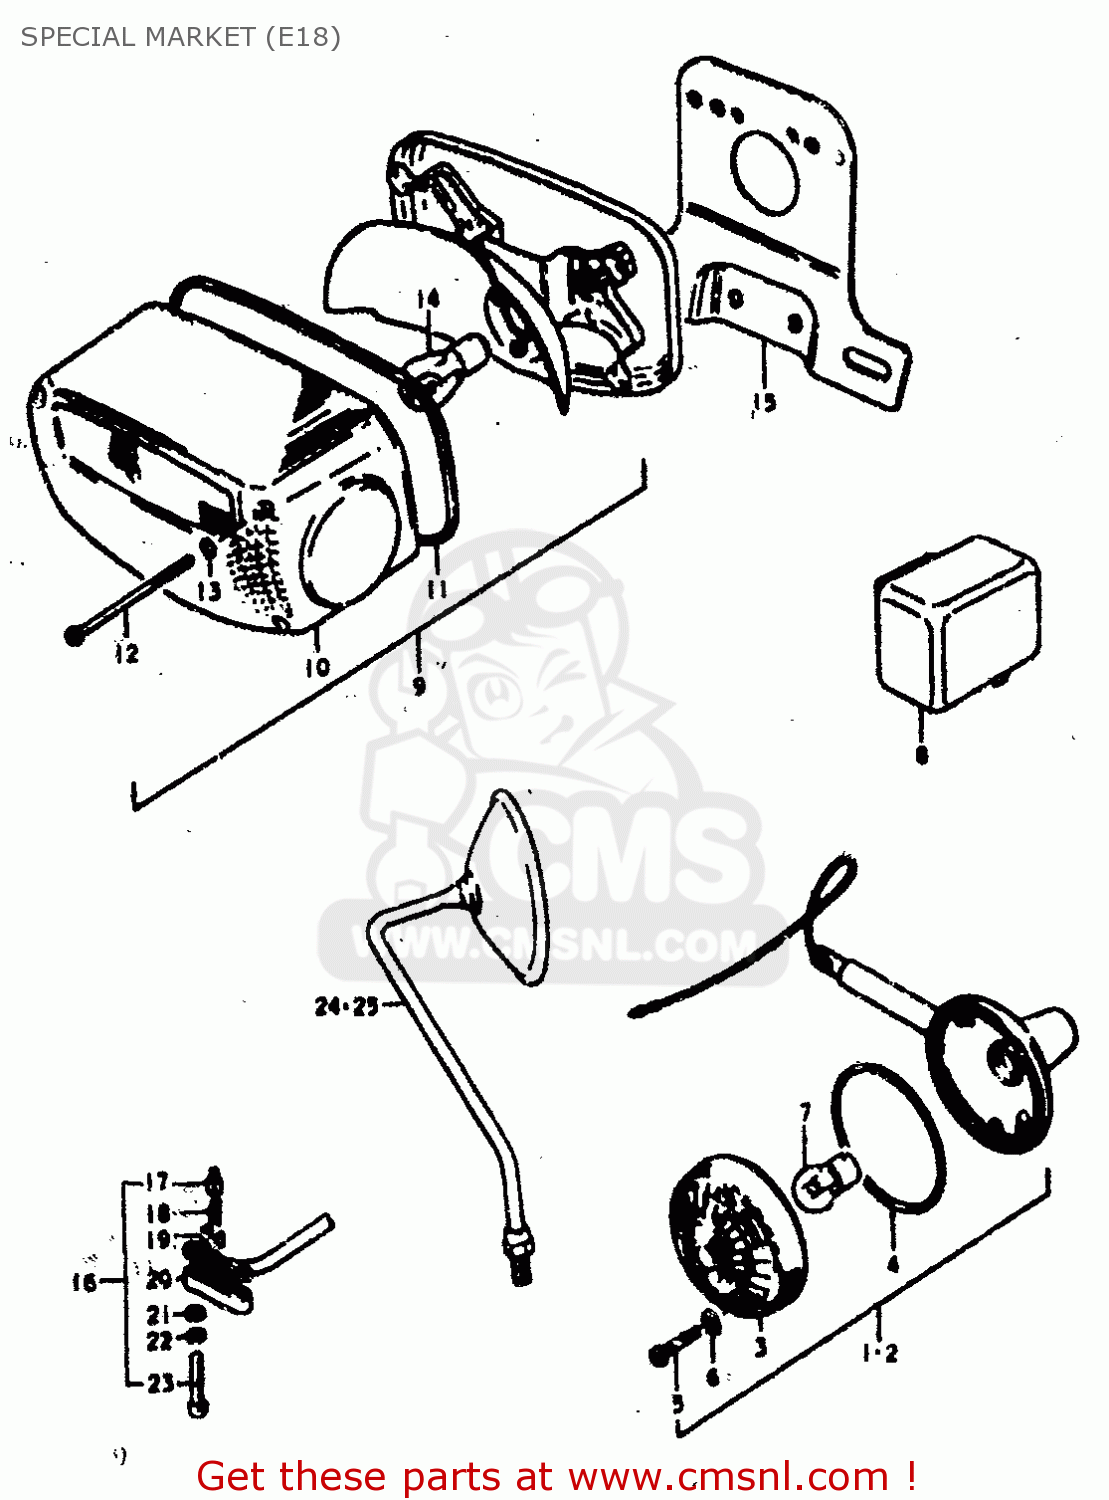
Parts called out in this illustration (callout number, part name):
1	LAMP ASSY, FRONT TURN SIGNAL
2	LAMP ASSY, REAR TURN SIGNAL
3	LENS
4	GASKET (NAS)
5	SCREW
6	GASKET (NAS)
7	BULB 12V 21W
9	LAMP ASSY,REAR COMBINATION
10	LENS,REAR COMBINATION LAMP
11	GASKET (NAS)
12	SCREW (4X55)
13	GASKET (NAS)
14	BULB(12V21/5W)
15	PLATE,LICENCE
16	SWITCH ASSY,STOP
17	HOLDER
18	SPRING
19	PLATE
20	COVER,FR BK TERMINAL BASE
21	WASHER
22	LOCK WASHER
23	SCREW
24	MIRROR,REAR VIEW RH
25	MIRROR,REAR VIEW LH
